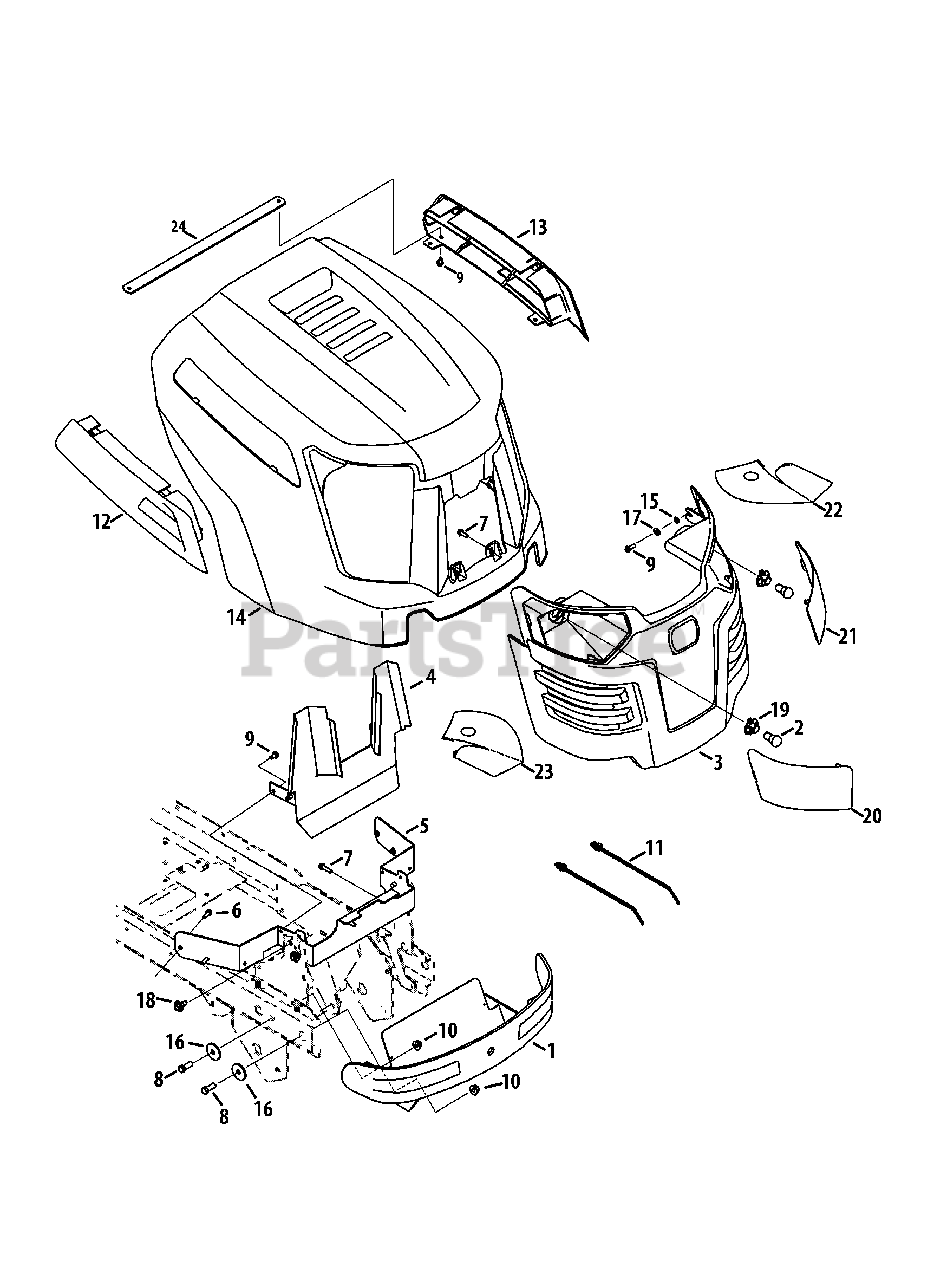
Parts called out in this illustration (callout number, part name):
1	Front Bumper Assembly
4	Heat Shield
5	Hood Pivot Bracket
6	Hex Washer Screw, 1/4 x .750
7	Hex Washer Screw, 5/16-14 x 1.00
8	Hex Screw, 3/8-16 x 1.00
9	Hex Washer Screw, 1/4-20 x 0.500
10	Flange Lock Nut, 3/8-16
11	Cable Tie, 7.5
12	RH Hood Scoop
13	LH Hood Scoop
14	Hood
15	Lock Washer, 1/4
16	Flat Washer, .390 x 1.500 x .134
17	Flat Washer, .271 x .630 x .065
18	Shoulder Screw, 5/16-18 x .43 x .29
19	1/4-turn Socket
20	RH Hood Lens
21	LH Hood Lens
22	Left Lens Reflector Label
23	Right Lens Reflector Label
